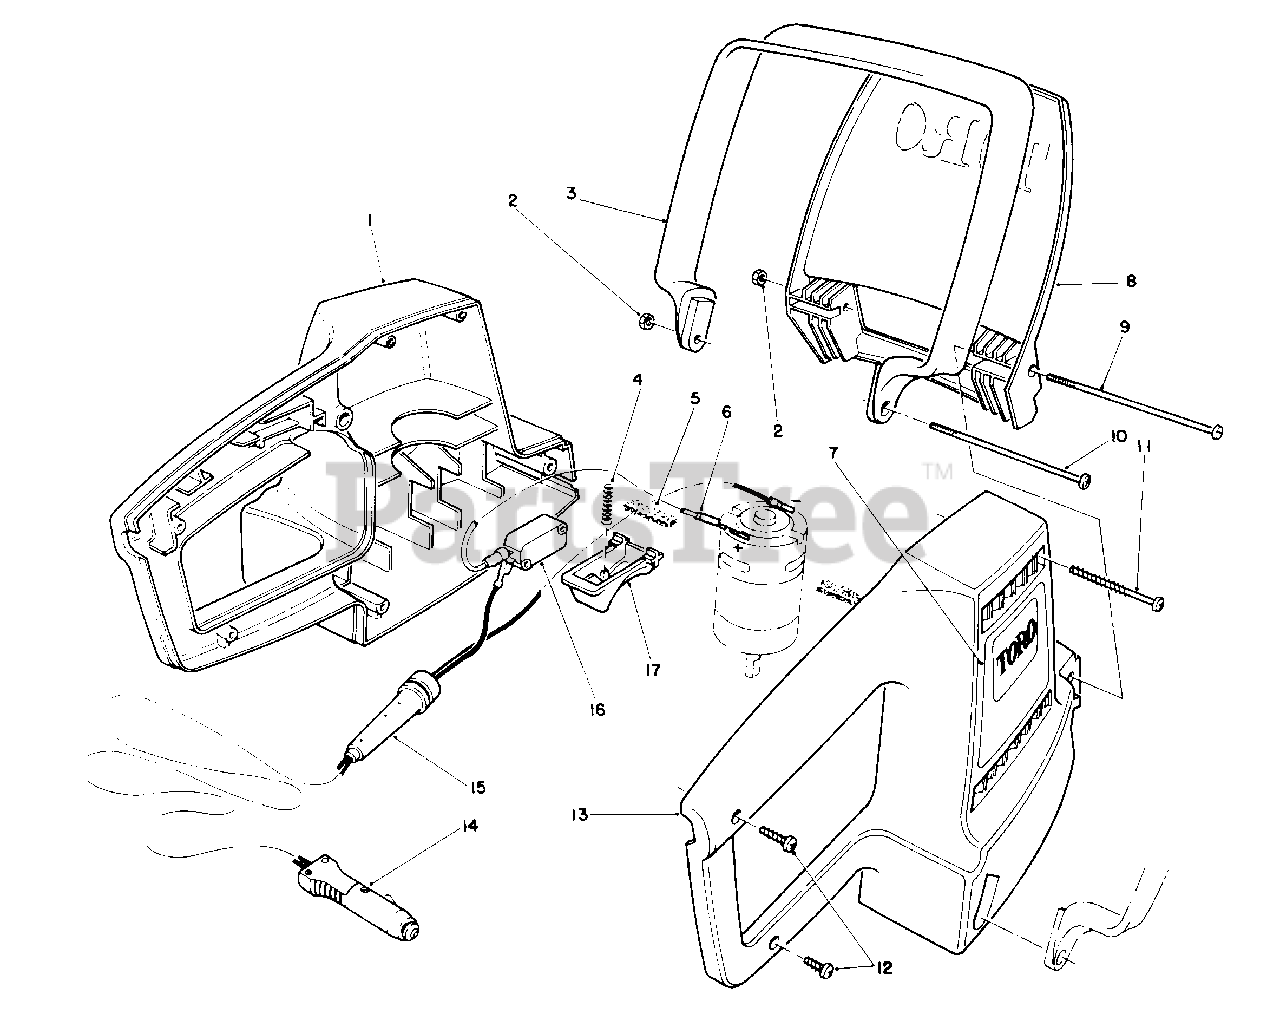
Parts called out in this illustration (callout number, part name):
1	Housing-Handle, L.H.
3	Handle-Assist
6	Wire Assembly
7	Decal-Toro
11	Screw-Thread Forming
12	Screw-Thread Forming
13	Housing-Handle, R.H.
14	Cord-Handle
15	Relief-Strain
17	Trigger-Switch
